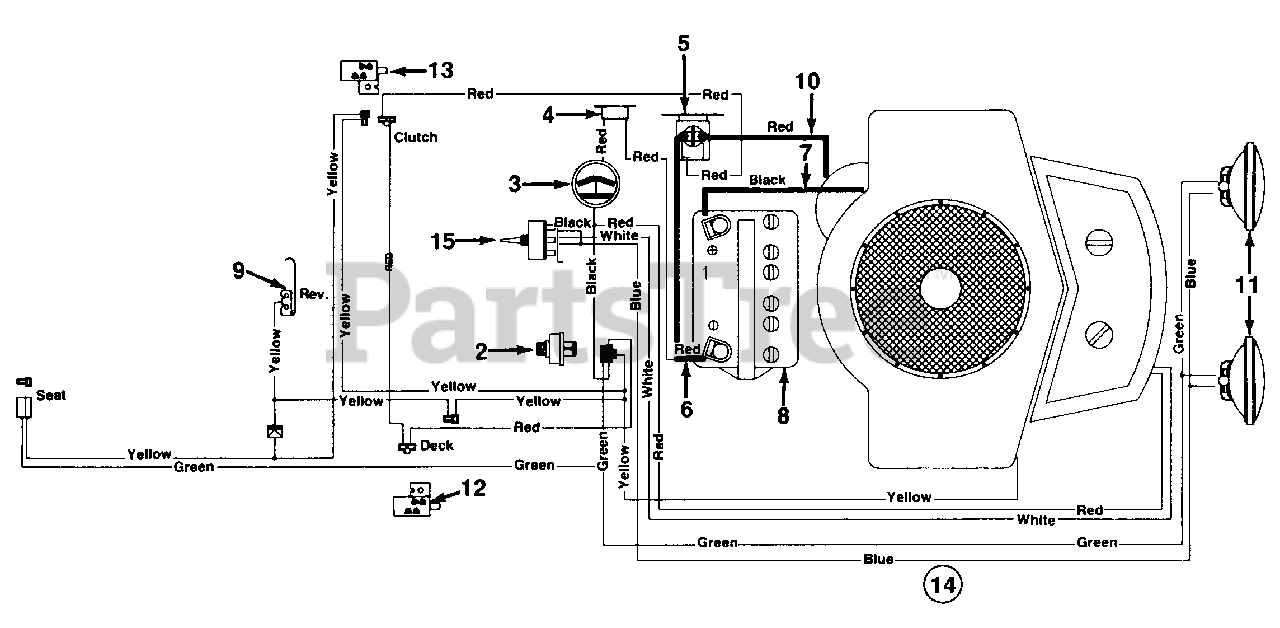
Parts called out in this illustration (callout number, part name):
2	Ignition Switch
3	Ammeter
4	Circuit Breaker
5	Solenoid
6	Electric Wire
7	Electric Wire
8	Battery
9	Spring Switch
10	Electric Wire
11	Headlights
12	Safety Switch
13	Safety Switch
14	Wire Harness
15	Light Switch
